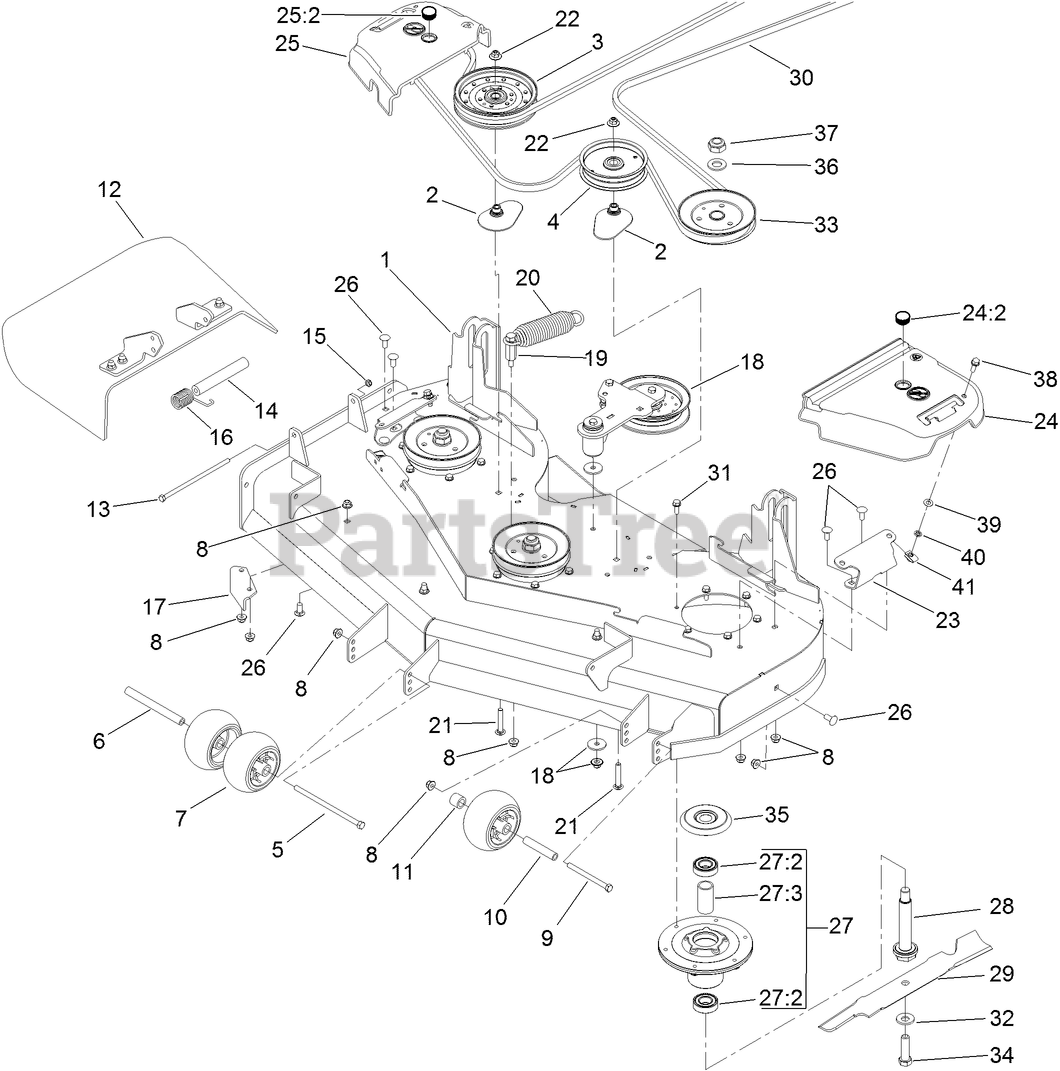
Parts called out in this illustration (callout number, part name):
1	DECK DECAL ASM
2	SPACER-PULLEY
4	PULLEY-IDLER
5	SCREW-HH
6	SPACER-WHEEL
7	ROLLER-SCALP, ANTI
8	NUT-HF, NI
9	SCREW-HH
10	TUBE-SPANNER
11	TUBE-SPACER
12	DEFLECTOR ASM
13	SCREW-HH
14	SPACER
15	NUT-LOCK, NI
16	SPRING-TORSION
17	BAFFLE-DISCHARGE
18	IDLER ARM ASM
19	ANCHOR-SPRING, TALL
21	BOLT-CARR, SHORT NECK
22	NUT-FLANGE, NI
23	BRACKET-COVER, BELT
24	LH BELT COVER ASM
24:2	PLUG-PLASTIC
25	RH BELT COVER ASM
25:2	PLUG-PLASTIC
26	SCREW-CARR
27	SPINDLE ASM
27:2	BEARING-BALL
27:3	SPACER-BEARING
28	SPINDLE-SHAFT
29	BLADE-HI FLO, 16.50 INCH
31	SCREW-TAPTITE
33	PULLEY-B SECTION
34	SCREW-BLADE
35	SHIELD-BEARING
36	WASHER
37	NUT-LOCK, NI
38	SCREW-HHF
39	WASHER-THRUST
40	NUT-PUSH
41	NUT-U
